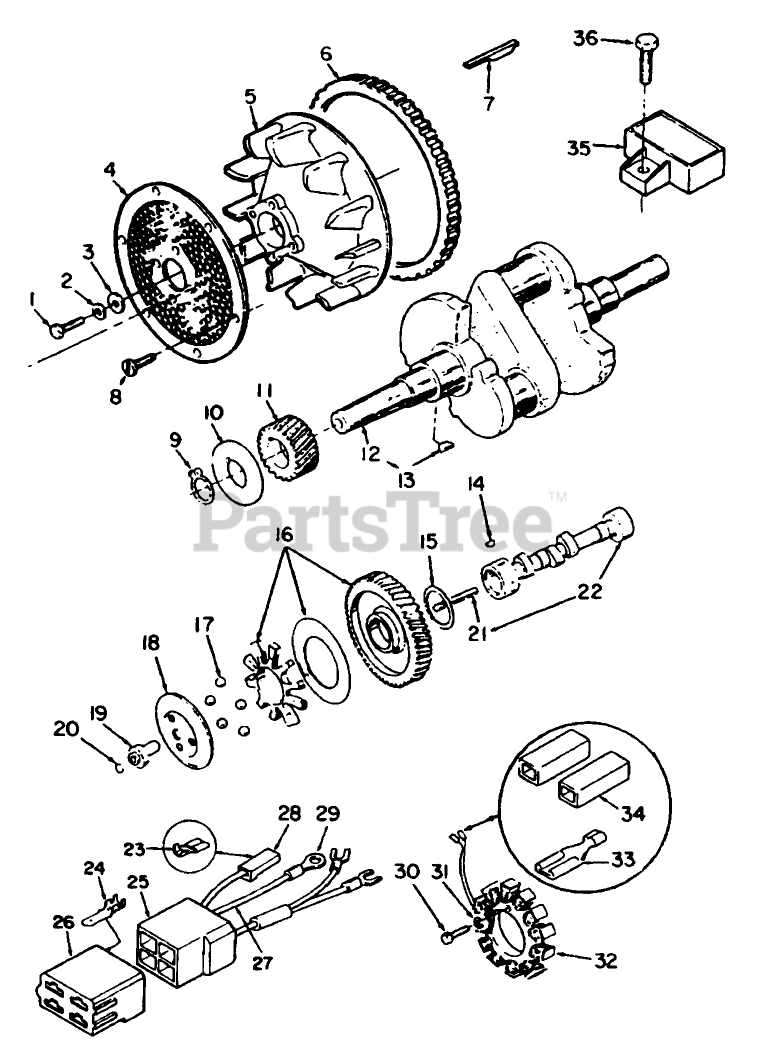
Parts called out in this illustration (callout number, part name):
1	SCREW
2	WASHER-LOCK
3	WASHER-FLAT
4	AIR INLET SCREEN
5	Flywheel (Incl. Ref. #6)
7	KEY-FLYWHEEL
8	LOCK SCREW
10	WASHER
12	Crankshaft (Incl. Ref. #13)
15	WASHER-THRUST
16	GEAR ASM
17	BEARING
18	CUP-GOVERNOR
19	HUB-GOVERNOR CUP
21	PIN-CENTER
22	Camshaft (Incl. Ref. #21)
23	RECEPTACLE TERMINAL
24	TAB TERMINAL
25	RECEPTACLE HOUSING
26	TAB HOUSING
27	ENGINE WIRING HARNESS
28	RECEPTACLE HOUSING
29	RING TERMINAL
30	SCREW
31	WASHER-LOCK
32	Stator
33	TERMINAL
34	Body-Terminal
35	Regulator
36	SCREW-HWH
